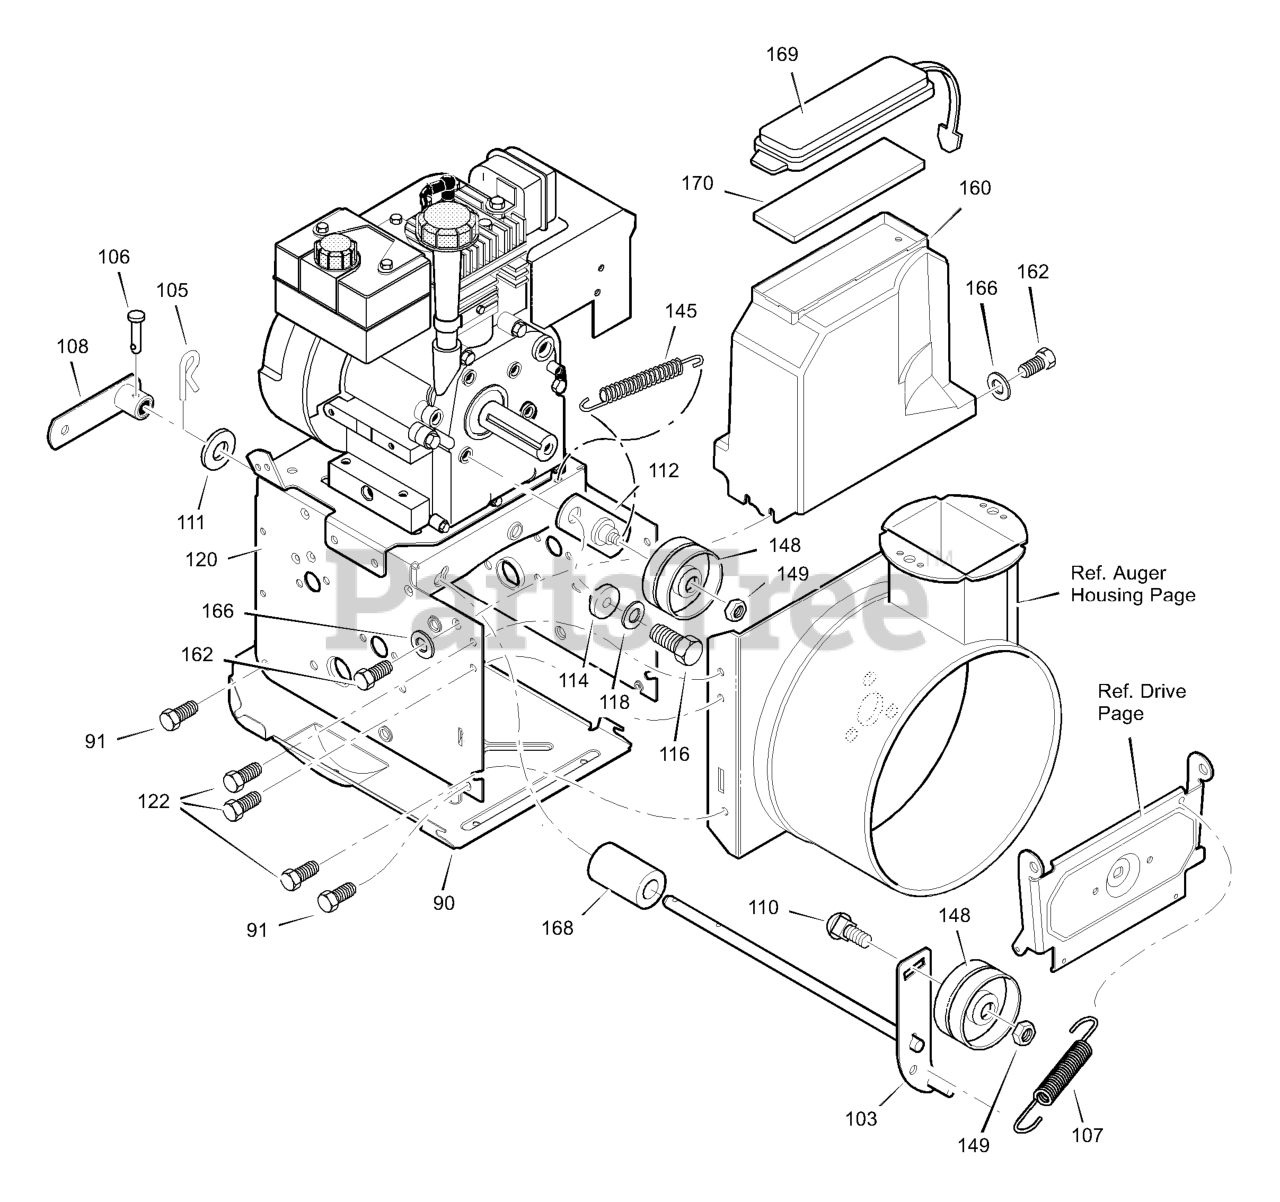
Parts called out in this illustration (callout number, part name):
90	COVER, BOTTOM
91	SCREW, 1/4-20X .63
103	IDLER ASSEMBLY, AUGER
105	PIN, HAIR .38DIAX1.64LG
106	PIN, KLIK 3/16" DIA
107	SPRING, TENSION
108	ASSY., SPRING ATTACH
110	BOLT, 3/8-16X1.25 CARR.
111	WASHER, FLAT
112	BRACKET ASSEMBLY, IDLER
114	BUSHING, IDLER BRACKET
116	SCREW 5/16-24 X .75
118	WASHER, SPLIT
122	SCREW, TAP 5/16-18 X .50
145	SPRING, IDLER TRACTION DRIVE
148	PULLEY, IDLER
149	NUT, JAM 3/8-16
160	COVER, BELT
162	SCREW, HEX HEAD
166	WASHER, FLAT
168	SPACER, AUGER BRACKET
169	COVER,TOOLBOX
170	PAD, FOAM
